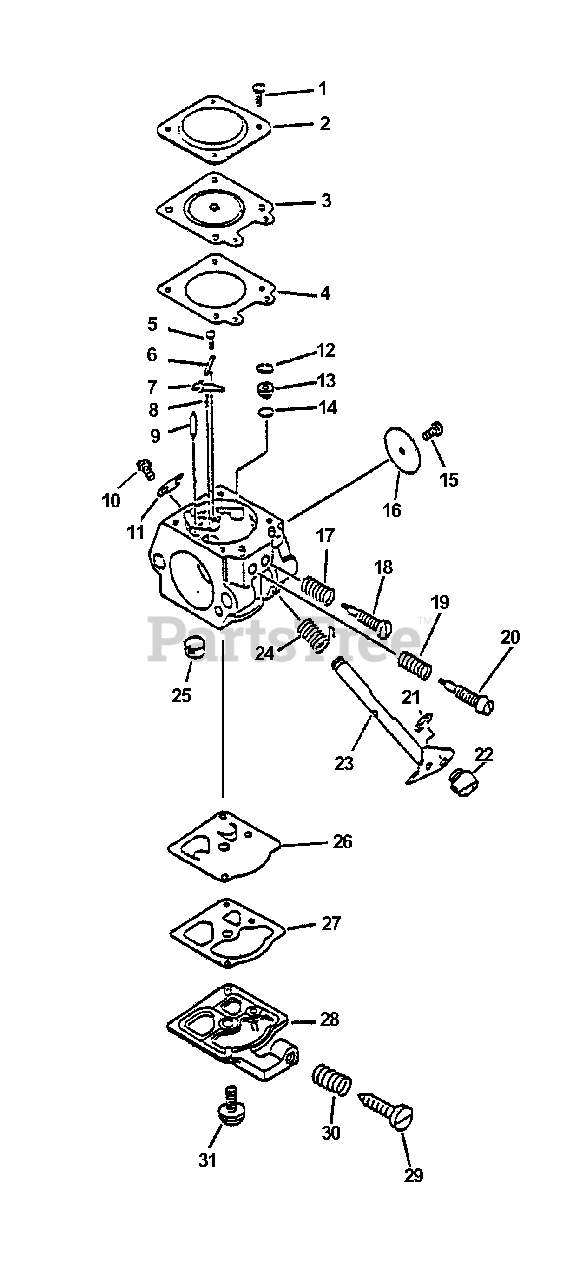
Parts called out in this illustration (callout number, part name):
1	SCREW
2	COVER, METERING
3	DIAPHRAGM, METERING
4	GASKET, METERING
5	SCREW, METERING LEVER PIN
6	PIN, METERING LEVER
7	LEVER, METERING
8	SPRING, METERING LEVER
9	VALVE, INLET NEEDLE
10	SCREW
11	RING, RETAINING
12	RING, RETAINING
13	JET - 40
14	O-RING
15	SCREW, VALVE
16	VALVE, THROTTLE
17	SPRING, LOW SPEED NEEDLE
18	NEEDLE - LOW SPEED
19	SPRING, HIGH SPEED NEEDLE
20	NEEDLE - HIGH SPEED
21	RING, RETAINING
23	SHAFT, THROTTLE
24	SPRING, THROTTLE SHAFT
25	STRAINER
26	DIAPHRAGM, PURGE
27	GASKET, PURGE
28	COVER, PUMP
29	SCREW, IDLE ADJUST
30	SPRING, IDLE ADJUST
31	SCREW, PUMP COVER
